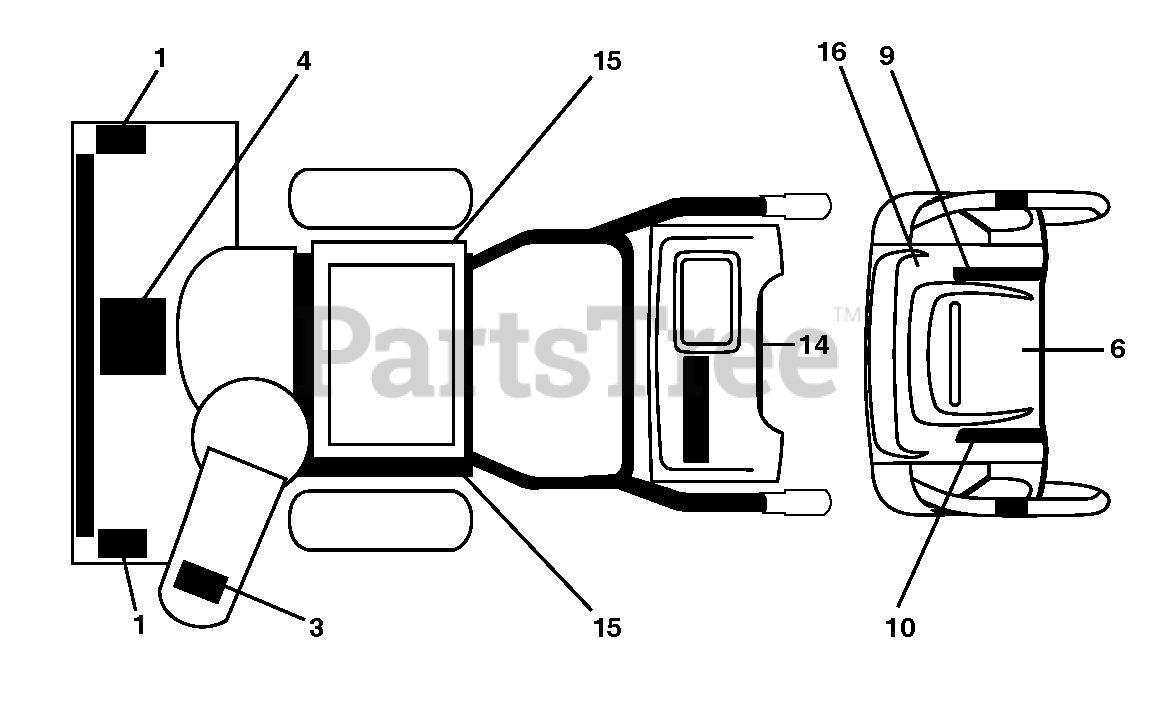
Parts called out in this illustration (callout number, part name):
1	DECAL.AUGER.SAFETY.
3	DECAL.CHUTE.SAFETY.
4	DECAL.AUGER."
9	DECAL CONSOLE DECAL DECAL.SNOW
10	DECAL CONSOLE DECAL DECAL.SNOW
14	DECAL.NOISE.LEVEL.105DB/CE.EAC
15	DECAL.BELT.GUARD.
16	DECAL.CONSOLE.HAND.WARMER
